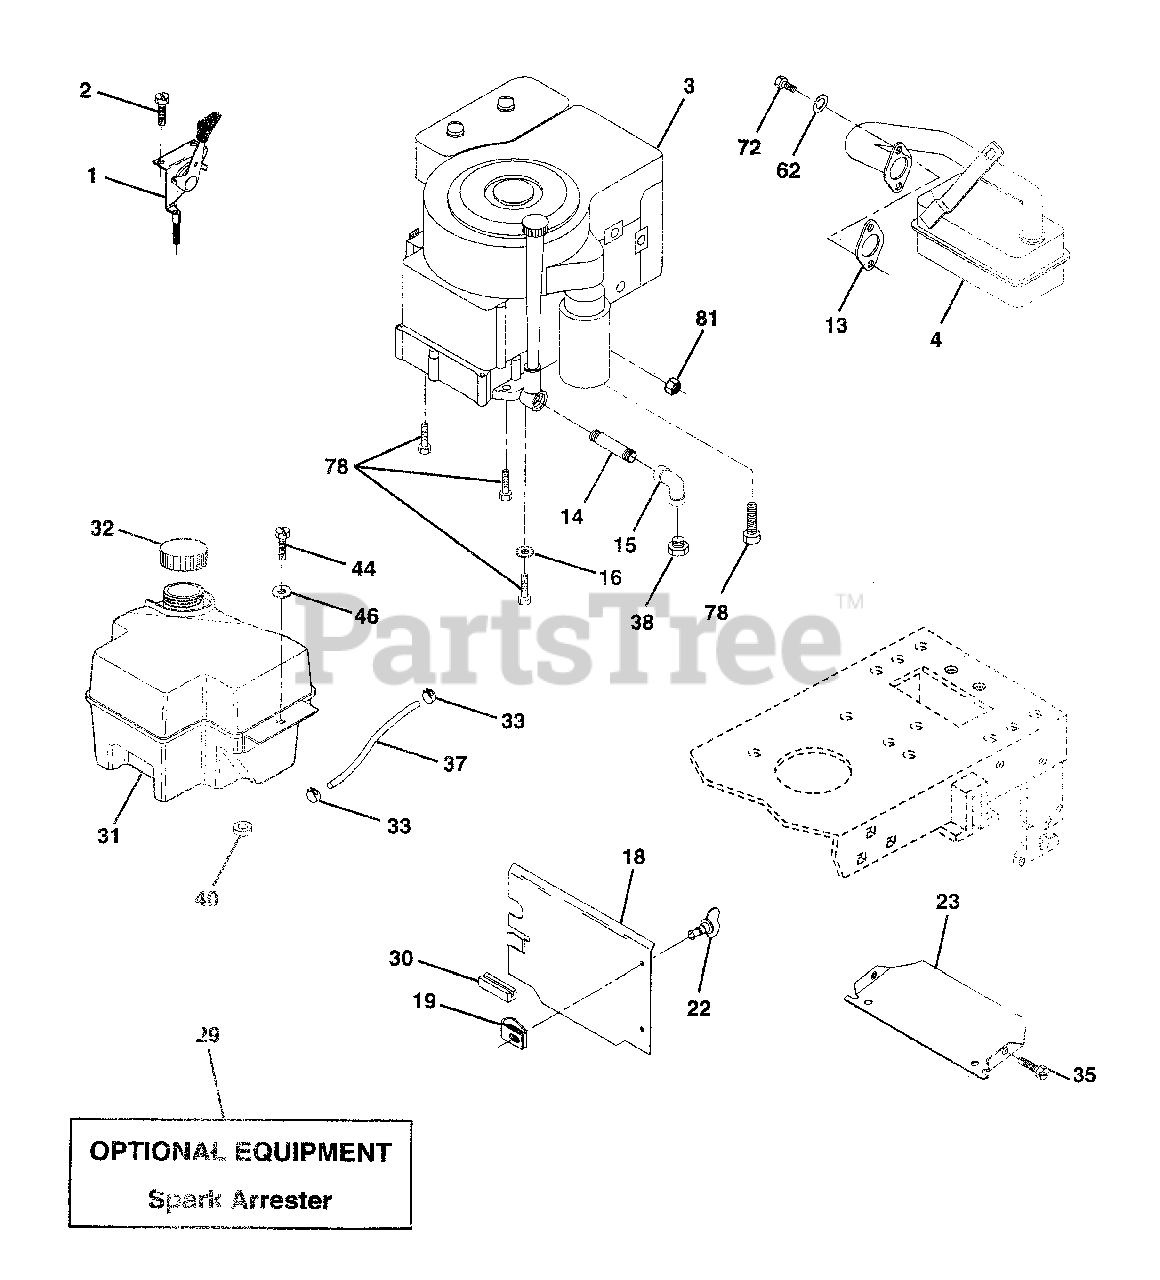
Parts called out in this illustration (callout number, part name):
1	Control Th/ch 23 LH Flag
2	Screw Hex Thd Cut 1/4-20x5/8 T
4	Muffler LT B&S 14 HP IC OHV
13	Gaskt Eng 1.313 ID Tin Plated
14	Nipple Pipe 3/8 Npt X 3-1/2
15	Elbow Std 90 Degree 3/8-18 Npt
16	Washer Lock Ext Tooth 3/8
18	Shield Heat LT
19	Receptacle 1/4 Turn Dacrotized
22	Stud 1/4 Turn
23	Shield Browning
29	Kit Spark Arrestor (Flat Scrn)
30	Pinchwelt Black
31	Tank Fuel Front 2 00
32	Cap Asm Fuel w/sym Vented
33	Clamp Hose Black
35	Screw Thdrol 5/16-18 x 3/4
37	Line Fuel 20"
38	Plug Oil Drain
40	Bushing Snap Nyl Blk Fuel Line
44	Screw Hexwsh Thdrol 1/4-20x3/4
46	Washer 9/32 X 7/8 X 16 Ga
62	Washer Lock Hvy Hlcl Spr 5/16
72	Screw Hex Hd Cap 5/16-18 x 3/4
78	Screw Thdrol. 3/8-16 x 1-1/4 Tytt
81	Nut Flange 1/4-20 Starter Nut
